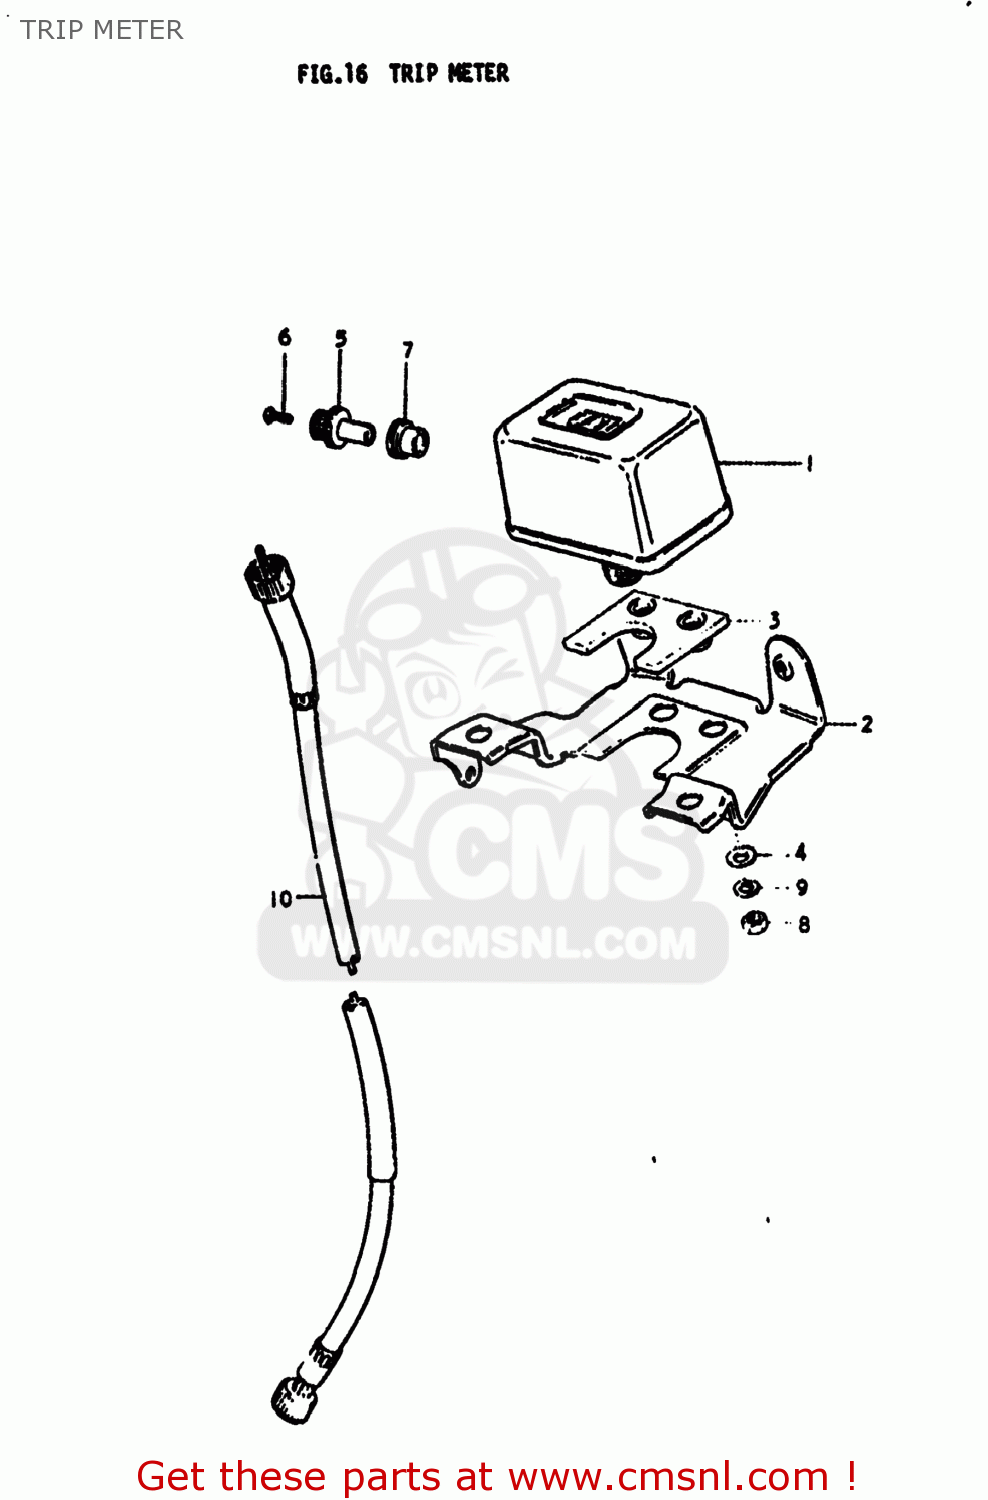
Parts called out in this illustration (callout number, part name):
1	TRIP METER
2	BRACKET,TRIPMETER
3	CUSHION,TRIPMETER
4	WASHER,METER
6	SCREW
7	COVER,TRIPMETER KNOB
8	NUT
9	LOCK WASHER
10	CABLE ASSEMBLY,SPEEDOMETER
